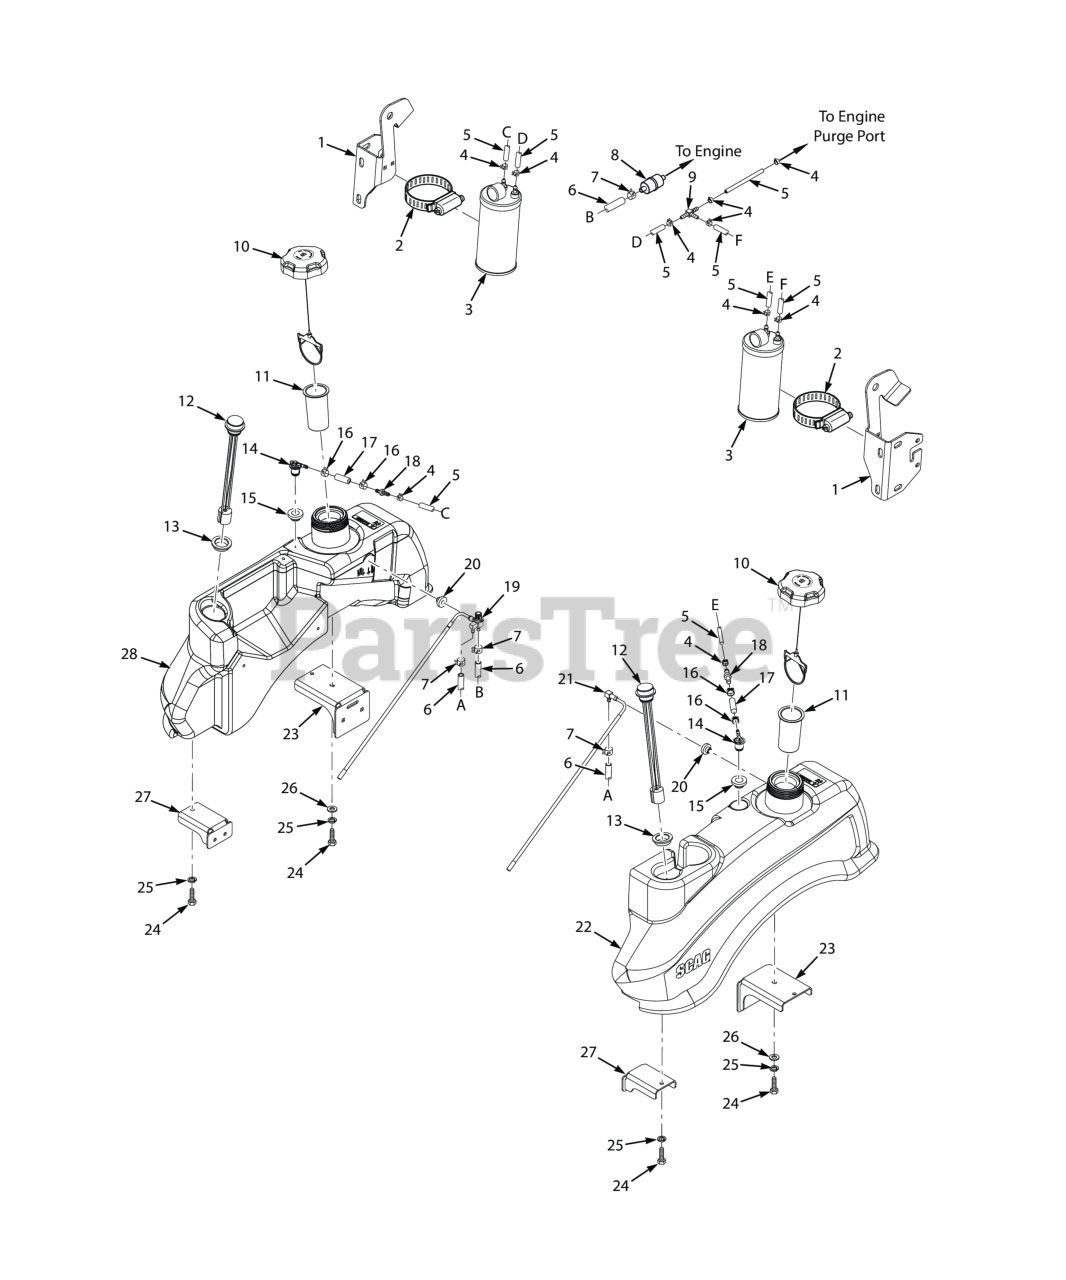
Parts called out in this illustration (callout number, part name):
1	ROPS Mount, LH
1	ROPS Mount, RH
2	Clamp, 3-1/2" Max. Dia.
3	Carbon Canister - SVR-36A / SVR-48V
3	Dust Filter, Carbon Canister
4	Clamp, Vapor Recovery Hose 3/16"
5	Hose, Vapor Recovery 3/16" (order by inch)
6	Fuel Hose, 1/4" I.D. Non-Perm (791DFI Fuel Return) - Order by Inch
7	Clamp, Fuel Hose 1/4" Hose I.D.
8	Fuel Filter
9	Tee, 3/16 x 3/16 x 3/16 Union, Hose Barb
10	Fuel Cap w/ Tether (E.P.A.)
10	Fuel Cap w/Tethered - California Models Only
11	Tube, Fuel Tank Insert - 4"
12	Fuel Gauge Assembly
13	Grommet, Fuel Gauge
14	Remote Vent, No Valve
15	Grommet, Viton,
16	CLAMP, FUEL HOSE(KAWASAKI ONLY)
17	Hose, 1/4" Vapor Recovery (order by inch)
18	Mender, 1/4 x 3/16 w/0.02 Hole
19	Fuel Tube Assembly, Includes Valve
20	Bushing, 0.56" Dia. Viton
21	Fuel Tube Assembly, LH
22	Fuel Tank Assembly, LH (incl. # 12, 14, 15, 20, 21)
23	Mounting Bracket, Fuel Tank Rear
24	BOLT, SERRATED FLANGE HEX HEAD 5/16-18 X 3/4"
25	Lockwasher, 5/16 (.317 x .586 x .078) Helical Spring
26	Flatwasher, 5/16-.375 x .875 x .083 (35BV & 37BV-EFI)
27	Mounting Bracket, Fuel Tank Front
28	Fuel Tank Assembly, RH (incl. #12, 14, 15, 19, 20)
